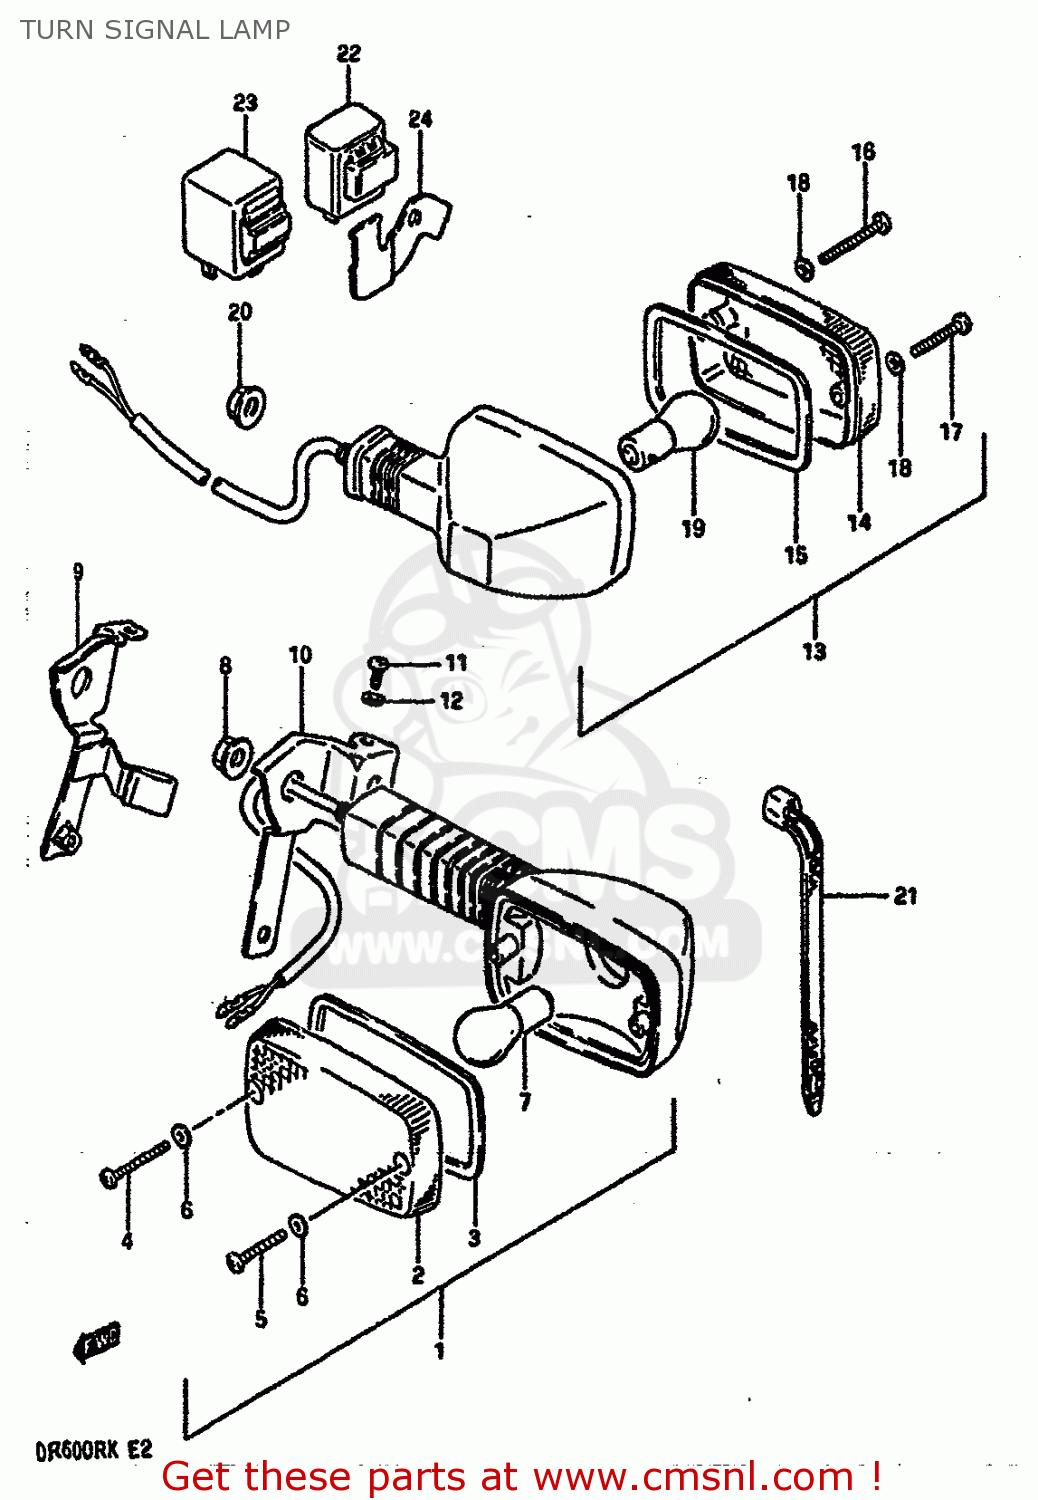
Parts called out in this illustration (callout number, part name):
1	LAMP ASSY,FR
2	LENS,FR
3	GASKET (NAS)
4	SCREW,TURN SIG LENS FITTING
5	SCREW
6	GASKET (NAS)
7	BULB(12V21W)
8	NUT
9	BRACKET,FRONT TURN SIGNAL
10	BRACKET,FRONT TURN SIGNAL
11	SCREW
12	WASHER,LOCK
13	LAMP ASSY,RR
14	LENS,RR
15	GASKET (NAS)
16	SCREW,TURN SIG LENS FITTING
17	SCREW
18	GASKET (NAS)
19	BULB(12V21W)
20	NUT
21	CLAMP(L:125)
22	RELAY ASSEMBLY,TURN SIGNAL
23	RELAY ASSY,TUR
24	BRACKET,TURN SIGNAL RELAY
